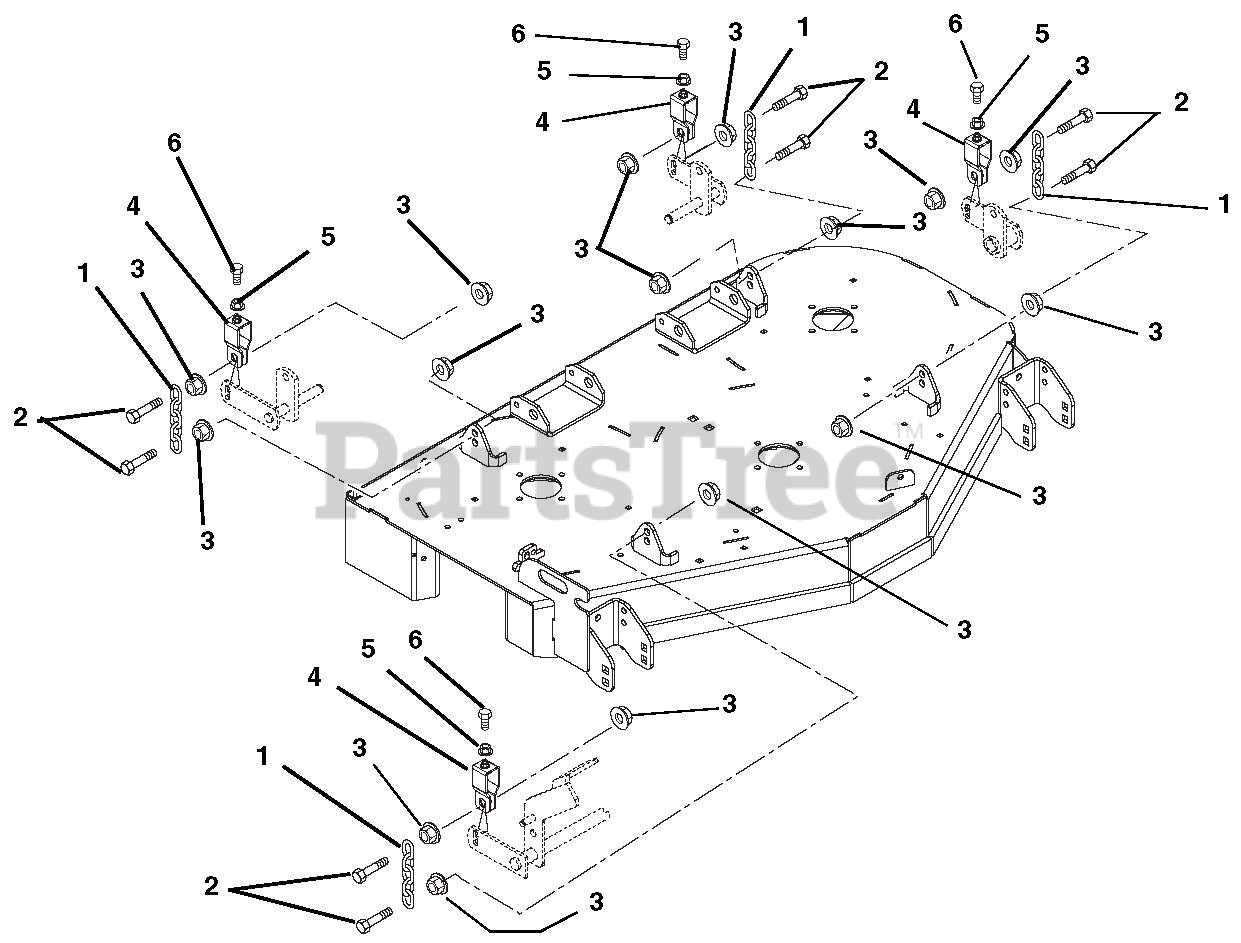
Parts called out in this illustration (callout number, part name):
1	Chain, Link
2	Bolt, Hex M12-1.75 x 50 CLS8.8
3	Nut, Spin Lock-Flange M12-1.75
4	Bracket, Deck Leveling
5	Nut, Jam .312-18
6	Bolt, Hex .312-18 x 2.00 Full Thread Grade 5
